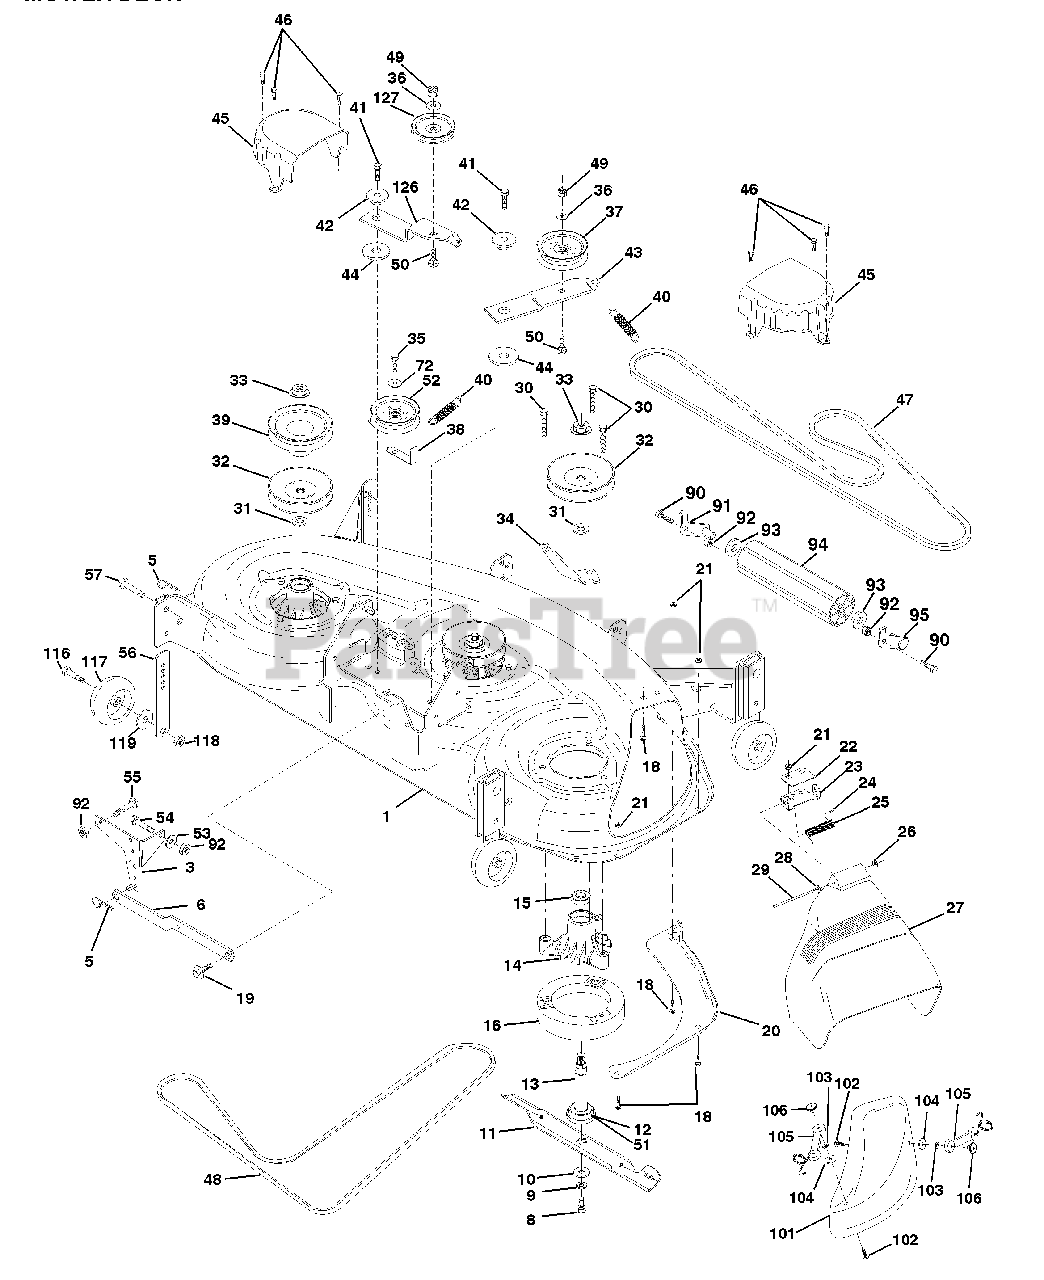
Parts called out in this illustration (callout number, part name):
1	Deck Weldment Mower HD 46 WAD
3	Bracket Asm., Sway Bar
5	Retainer Spring
6	Arm, Suspension, Rear (Sway Bar)
8	Bolt, Patched 3/8-24 x 1-1/4 Gr. 8
9	Washer, Lock Hvy., Unplated 3/8
10	Washer, Hard Blade, Mower Vented
11	Blade, 46" Mower Deck
12	Bearing, Ball, Mandrel #6204
13	Shaft Asm. w/Lower Bearing
14	Housing, Mandrel
15	Bearing, Ball, Mandrel
16	Stripper, Mower Round
18	Bolt, Carriage 5/16-18 x 5/8
19	Bolt, Hex Head, Shoulder 5/16-18
20	Baffle, Vortex Mower 46"
21	Nut, Crownlock 5/16-18 UNC
22	Stiffener, Bracket
23	Bracket, Deflector
24	Cap, Sleeve
25	Spring, Torsion, Deflector
27	Shield, Deflector Mower
28	Washer 11/32 x 5/8 x 16 Ga.
29	Rod, Hinge
30	Screw, Thdroll, Washer Head
31	Washer, Spacer Mower Vented
32	Pulley, Mandrel
33	Nut, Flg. Top Lock Cntr. 9/16
34	Anchor, Spring Deck 46"
35	Screw, Thdroll 3/8-16 x 1-3/4 Tytt
36	Washer 13/32 x 13/16 x 16 Ga.
37	Pulley, Idler, Flat
38	Keeper, Belt, Idler
39	Pulley, Idler, Driven
40	Spring, Secondary 44/46/50 Vent
41	Screw, Thdroll 3/8-16 x 1-1/4 Tytt
42	Spacer, Retainer
43	Arm, Idler Secondary
44	Washer, Hardened
45	Cover, Mandrel Deck
46	Screw, Thdroll. 1/4-20 x 5/8
47	V-Belt, Mower, Secondary
48	V-Belt, Mower, Primary
49	Nut, Crownlock 3/8-16 UNC
50	Bolt, Carriage 3/8-16 x 1-1/2 Gr. 5
51	Washer, Felt
52	Pulley Idler Flat 46 Pri. Drive
53	Washer 13/32 x 13/16 x 12 Ga.
54	Bolt Fin Hex 3/8-16unc x 1 Gr. 5
55	Bolt Rdhd Sqnk 3/8-16unc x 1
56	Bar Pnt Adjusting Wheel Gauge
57	Pin Head Rivet
72	Washer 13/32 x 1 x 16 Ga.
90	Bolt, Fin, Hex 3/8-16 UNC x 1
91	Bracket, Asm Noseroller, LH
92	Nut, Lock, Hex w/Ins 3/8-16UNC
93	Washer 17/32 x 7/8 x 16 Ga.
94	Roller, Nose 38 & 42
95	Bracket, asm Noseroller RH
101	Cover, Mulching
102	Screw
103	Washer, Lock #10
105	Latch Asm. Bagger
106	Nut, Weld
116	Bolt, Shoulder
117	Gauge Wheel
118	Nut, Centerlock 3/8-16 UNC
119	Washer 3/8 x 7/8 x 14 Ga.
126	Arm, Idler, Primary Deck 46"
127	Pulley, Idler, V-Groove Dim. 4.25
